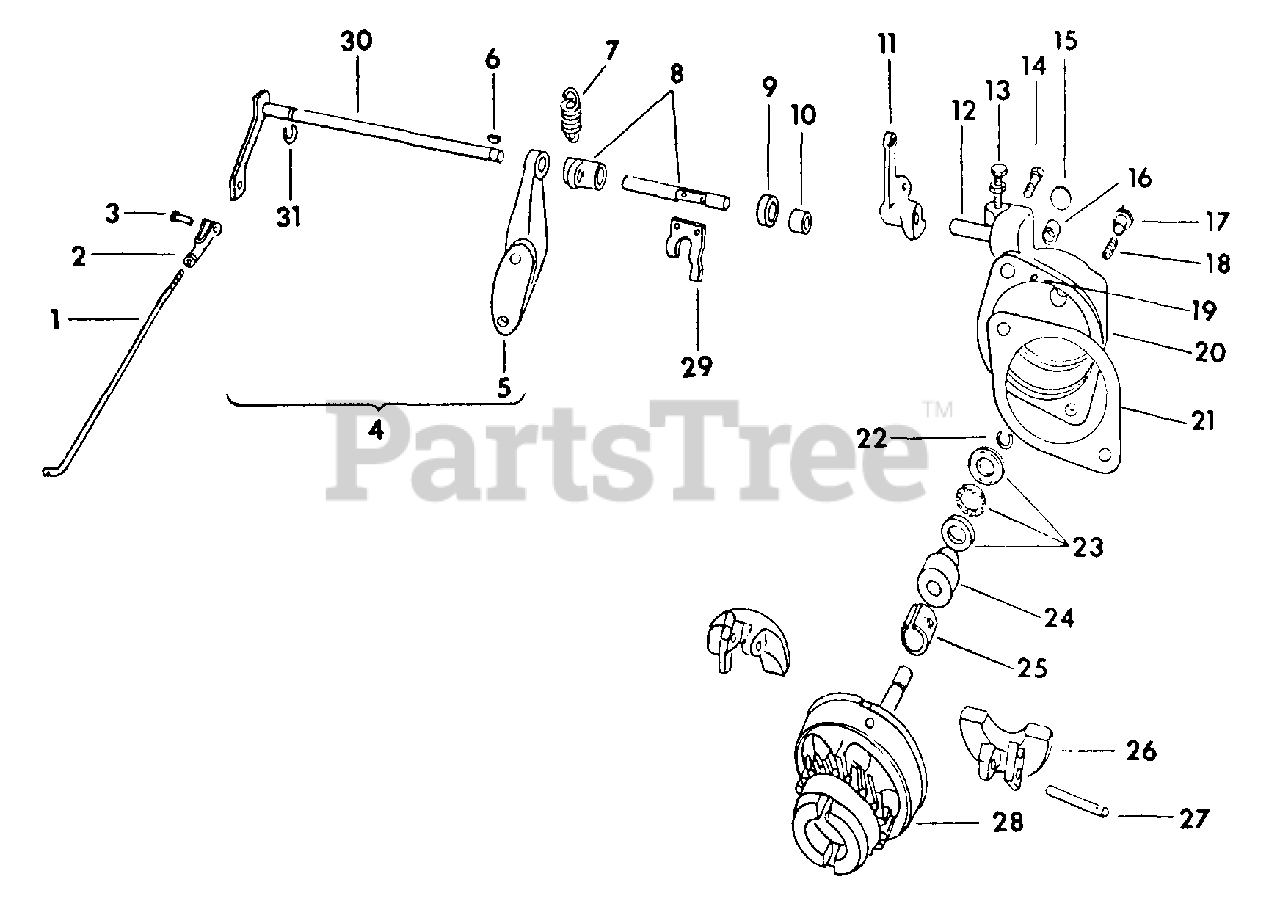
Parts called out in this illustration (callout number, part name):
1	ROD, GOVERNOR CONNECTING
2	CLEVIS, 10-32 SHORT ADJ ROD END - GOVERNOR CONNECTING ROD
3	PIN, 3/16 X 19/32 ROD END - GOVERNOR CONNECTING ROD CLEVIS
4	EXTENSION ASSY, GOVERNOR ROCKSHAFT AND BRACKET
5	BRACKET, GOVERNOR ROCKSHAFT EXTENSION
6	KEY, 3/32 X 1/2 WOODRUFF
7	SPRING, GOVERNOR
8	ROCKSHAFT ASSY, GOVERNOR AND SPRING LEVER
9	SEAL, GOVERNOR ROCKSHAFT OIL
10	BEARING, GOVERNOR ROCKSHAFT
11	LEVER, GOVERNOR SPRING THROTTLE
12	SHAFT, GOVERNOR THROTTLE LEVER
13	SCREW, GOVERNOR SPEED CHANGE LEVER STOP
14	NUT USED IN THIS APPLICATION
15	PLUG, 5/8 EXPANSION - GOVERNOR HOUSING
16	BUSHING, GOVERNOR SHAFT
17	BODY, GOVERNOR BUMPER SPRING
18	SPRING, GOVERNOR BUMPER
19	PIN, GOVERNOR BASE DOWEL
20	HOUSING ASSY, GOVERNOR
21	GASKET, GOVERNOR HOUSING
22	RING, GOVERNOR SLEEVE STOP
23	BEARING, GOVERNOR THRUST BALL
24	SLEEVE, GOVERNOR THRUST
25	BUSHING, GOVERNOR BASE
26	WEIGHT, GOVERNOR
27	PIN, GOVERNOR WEIGHT
28	SHAFT, GOVERNOR W/CARRIER AND PIN
29	FORK, GOVERNOR TENSION
30	EXTENSION ASSY, GOVERNOR ROCKSHAFT
31	RING, GOVERNOR ROCKSHAFT EXTENSION STOP
